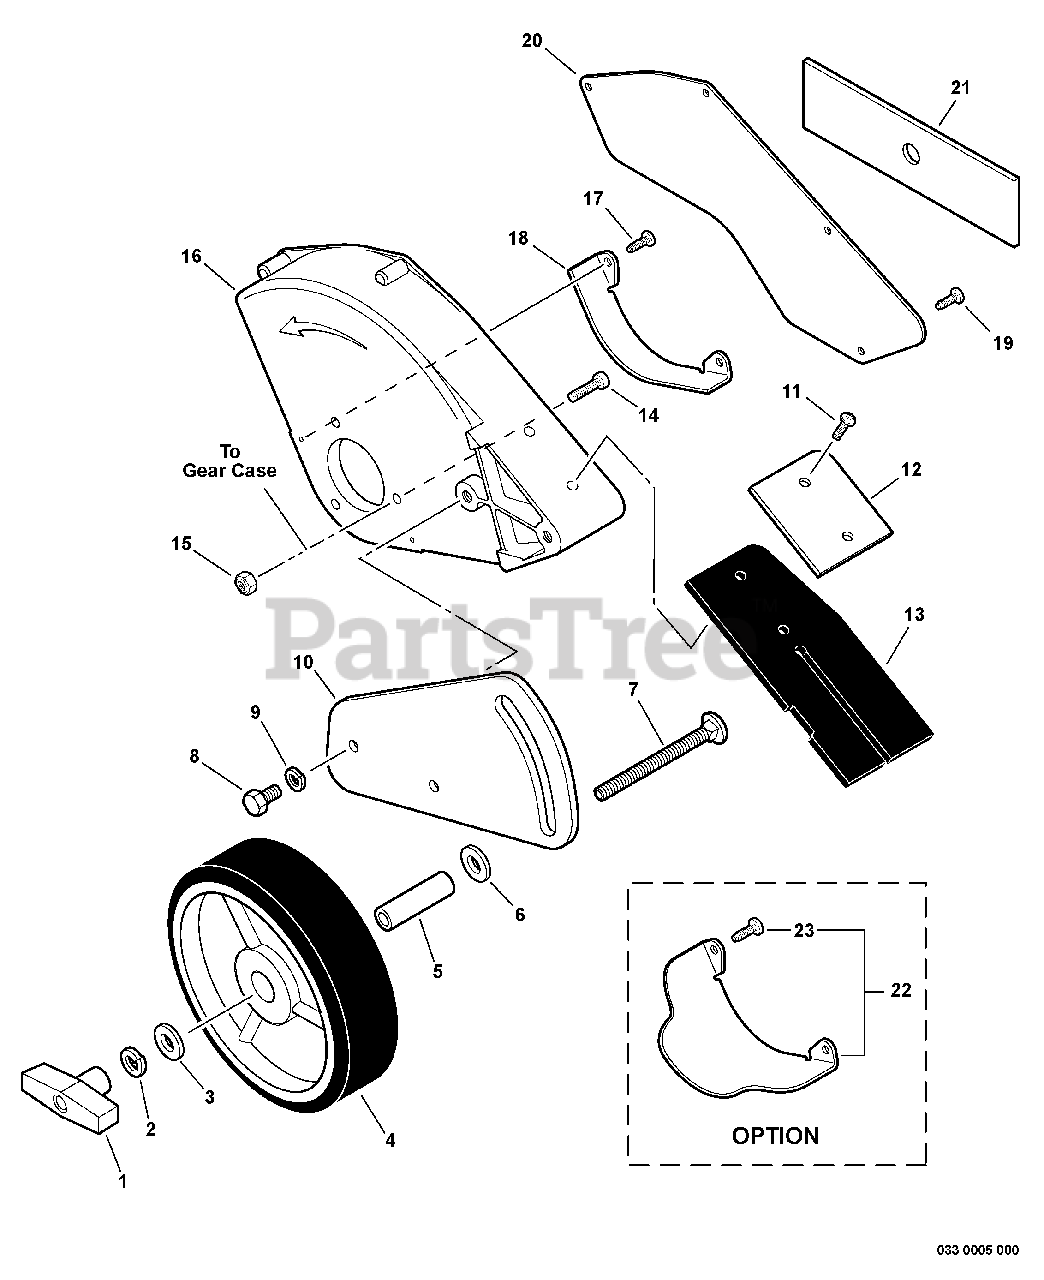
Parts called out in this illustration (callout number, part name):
1	WINGNUT - 5/16-18
2	LOCKWASHER - 8
3	WASHER - 8
4	WHEEL - 6X1.5
5	COLLAR - 12
6	WASHER - 10
7	BOLT - CARRIAGE
8	BOLT - 8X14
9	LOCKWASHER - 8
10	BRACKET, WHEEL
11	SCREW - 4X14
12	FLAP, DEBRIS
13	FLAP, DEBRIS
14	SCREW - 5X22
15	LOCKNUT - 5
16	NEW BLADE SHIELD
17	SCREW - 4X12
19	SCREW - 4X12
20	COVER, SHIELD
21	BLADE, EDGER
22	SHIELD GUARD KIT
23	SCREW - 4X12 -- TAPPING
